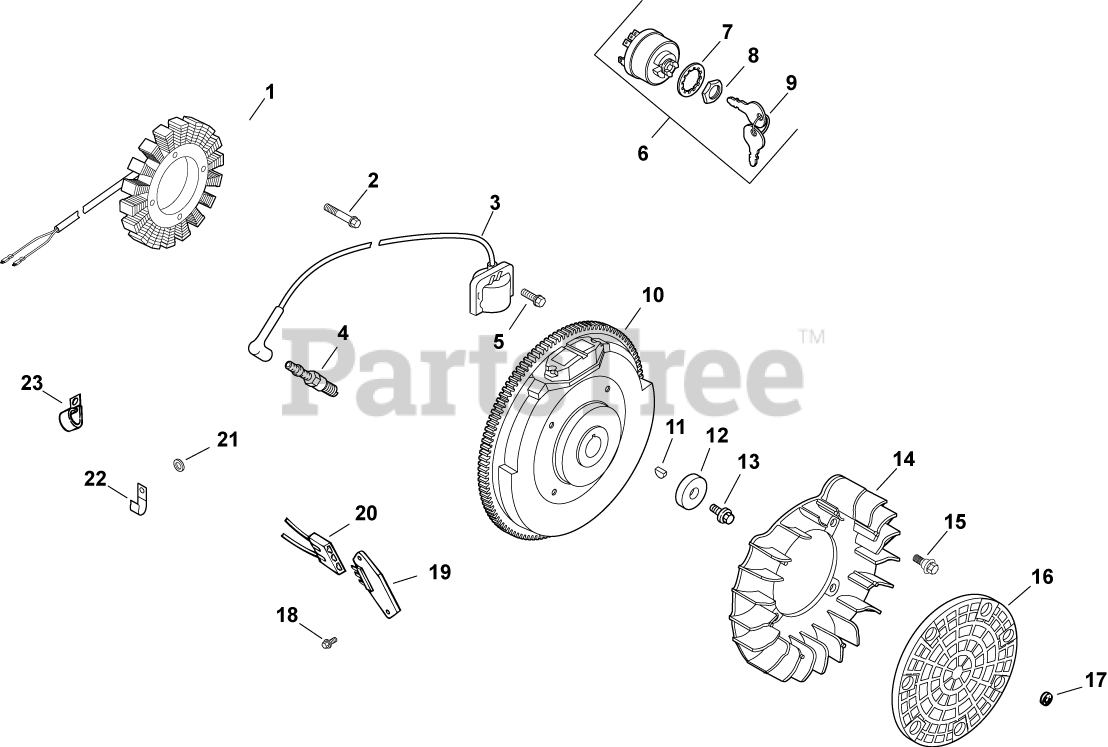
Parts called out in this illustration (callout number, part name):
1	KIT, 15 / 20 AMP STATOR
2	SCREW, M5X0.8X25 - (#25086402S)
3	KIT, MODULE IGNTN (CDI FIXED)
4	PLUG, SPARK (PRO SERIES)
5	SCREW, FLG THD FRM M5X.8X20-(#25086399S)
6	SWITCH ASSY, KEY (KM)-USE 25 099 32-S
7	WASHER, INTERNAL TOOTH
8	NUT, KEY SWITCH
9	KEY, SET -USE 48 340 01-S
10	FLYWHEEL, PAINTED-USE 24 025 55-S
11	KEY, 3/16" X 5/8"
12	WASHER, FLAT 13/32"
13	SCREW, FLG M10X1.5X45 - (#25086361S)
14	FAN - USE (#24 157 11-S)
15	BOLT, SHOULDER
16	SCREEN, GRASS
18	SCREW, PHL HD #11-16X7/8"
19	REG/RECTIFIER (20/25 AMP)-USE 25 403 20-
20	CONNECTOR, BODY (KM)-USE 25 155 41-S
21	WASHER, FLAT 1/4" (O.D. 1/2")
22	CLIP, CABLE
23	CLIP, TUBE & WIRING (KM)
